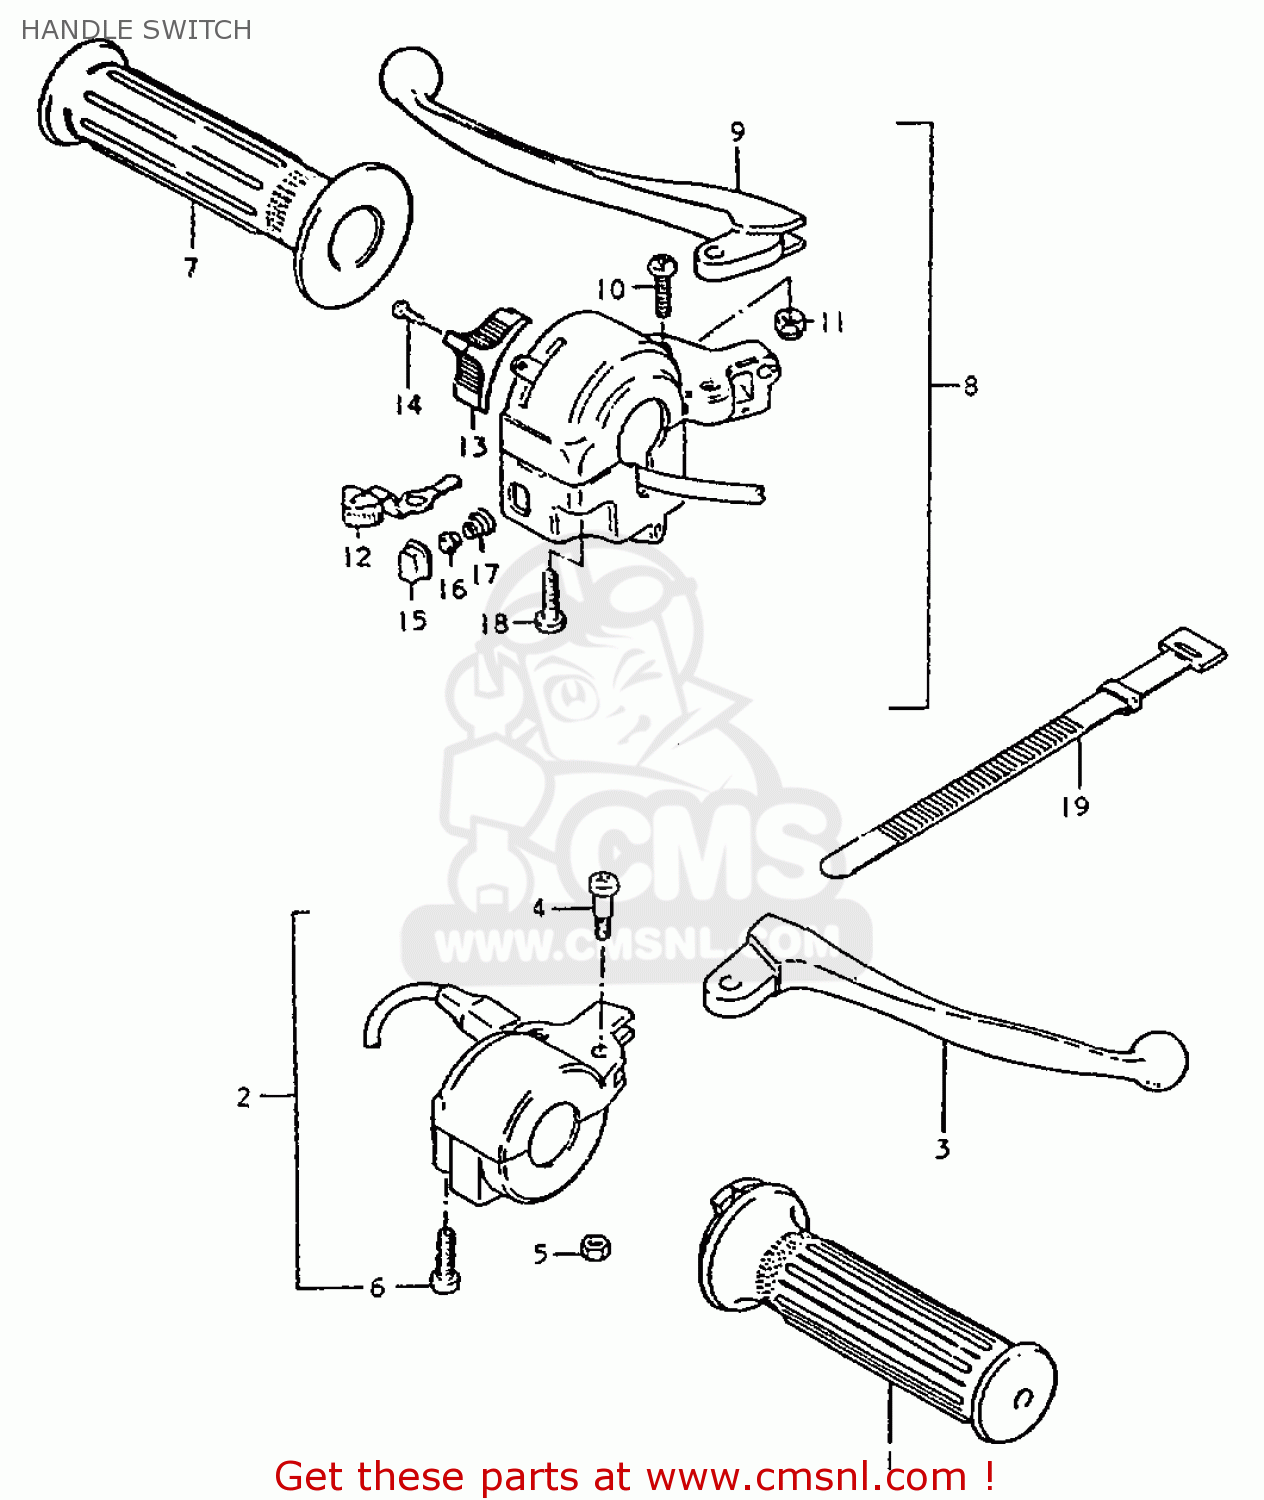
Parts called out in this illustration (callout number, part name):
1	GRIP,THROTTLE
2	BRAKE LEVER & SWITCH ASSY
3	LEVER
4	BOLT,LEVER
5	NUT,LEVER BOLT
6	SCREW
7	GRIP,L
8	LEVER ASSY,CLUTCH
9	LEVER
10	BOLT,LEVER
11	NUT,LEVER BOLT
12	KNOB,TURN SIGNAL SWITCH
13	KNOB
14	SCREW 3X6
15	BUTTON,HORN
16	CONTACT
17	SPRING
18	SCREW 5X20
19	CLAMP(L:120)
